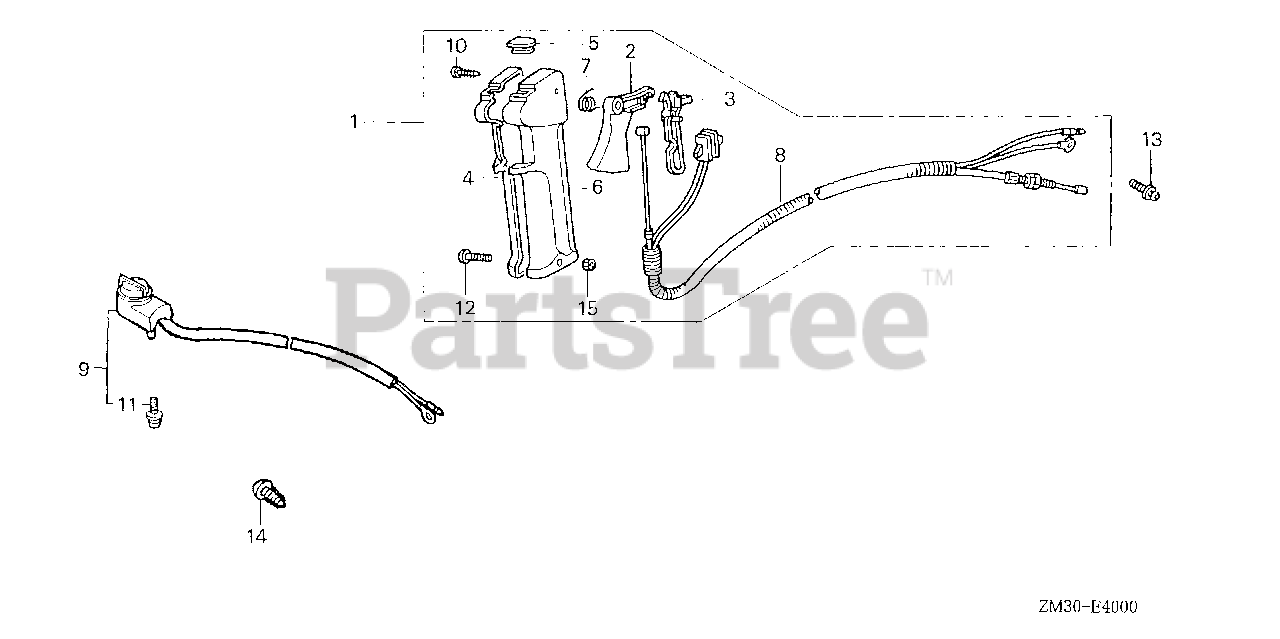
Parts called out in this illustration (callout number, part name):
9	SWITCH ASSY., ENGINE STOP
11	BOLT (3X12) (SEMS)
14	SCREW, TAPPING (3X8)
